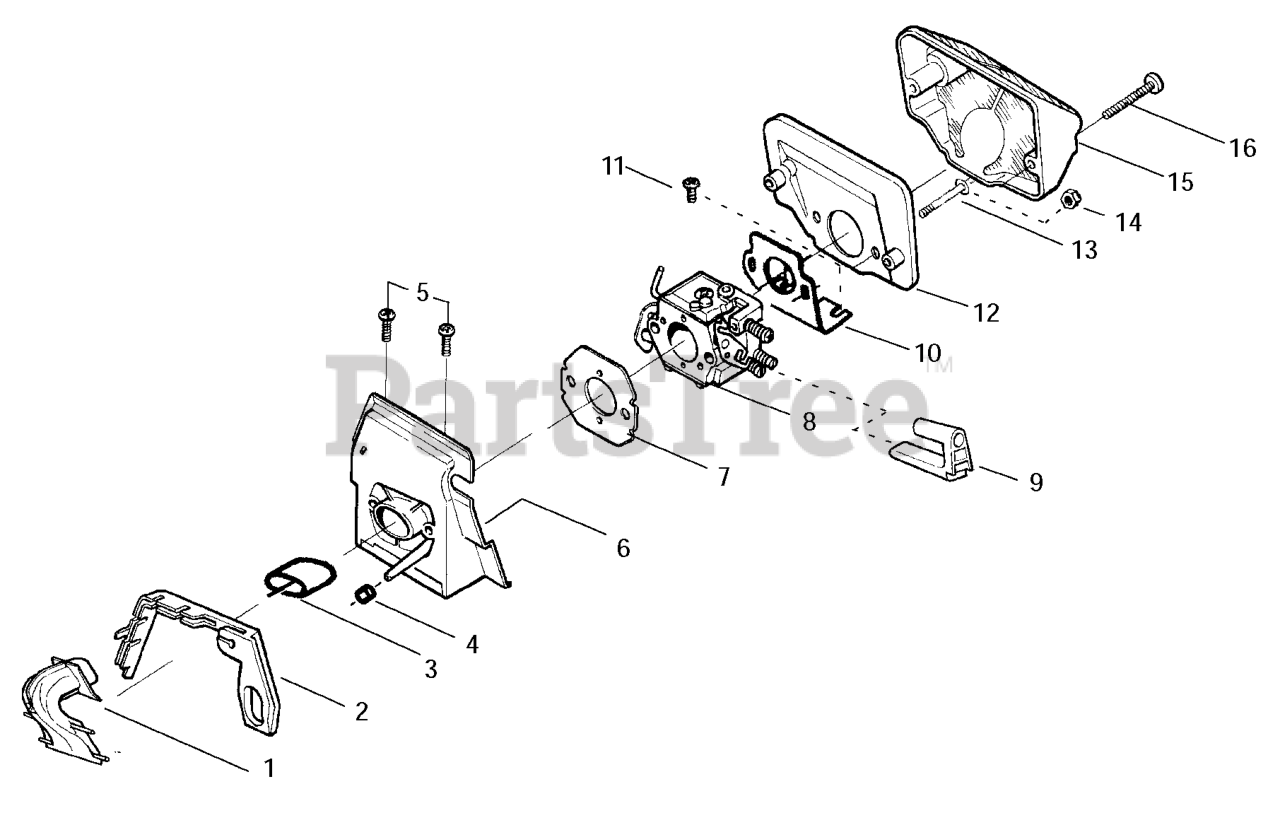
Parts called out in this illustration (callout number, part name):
1	INTAKE HORN
2	TURBO CLEAN SEAL
3	INTAKE PIPE
4	IMPULSE PIPE
6	CARB ADAPTOR
7	GSKT,CARB 36/41
8	CARBURETOR/EPA
8	CARBURETOR
9	GROMMET
12	AIR FILTER (BOTTOM)
13	STUD-CARBURETOR
15	AIR FILTER
